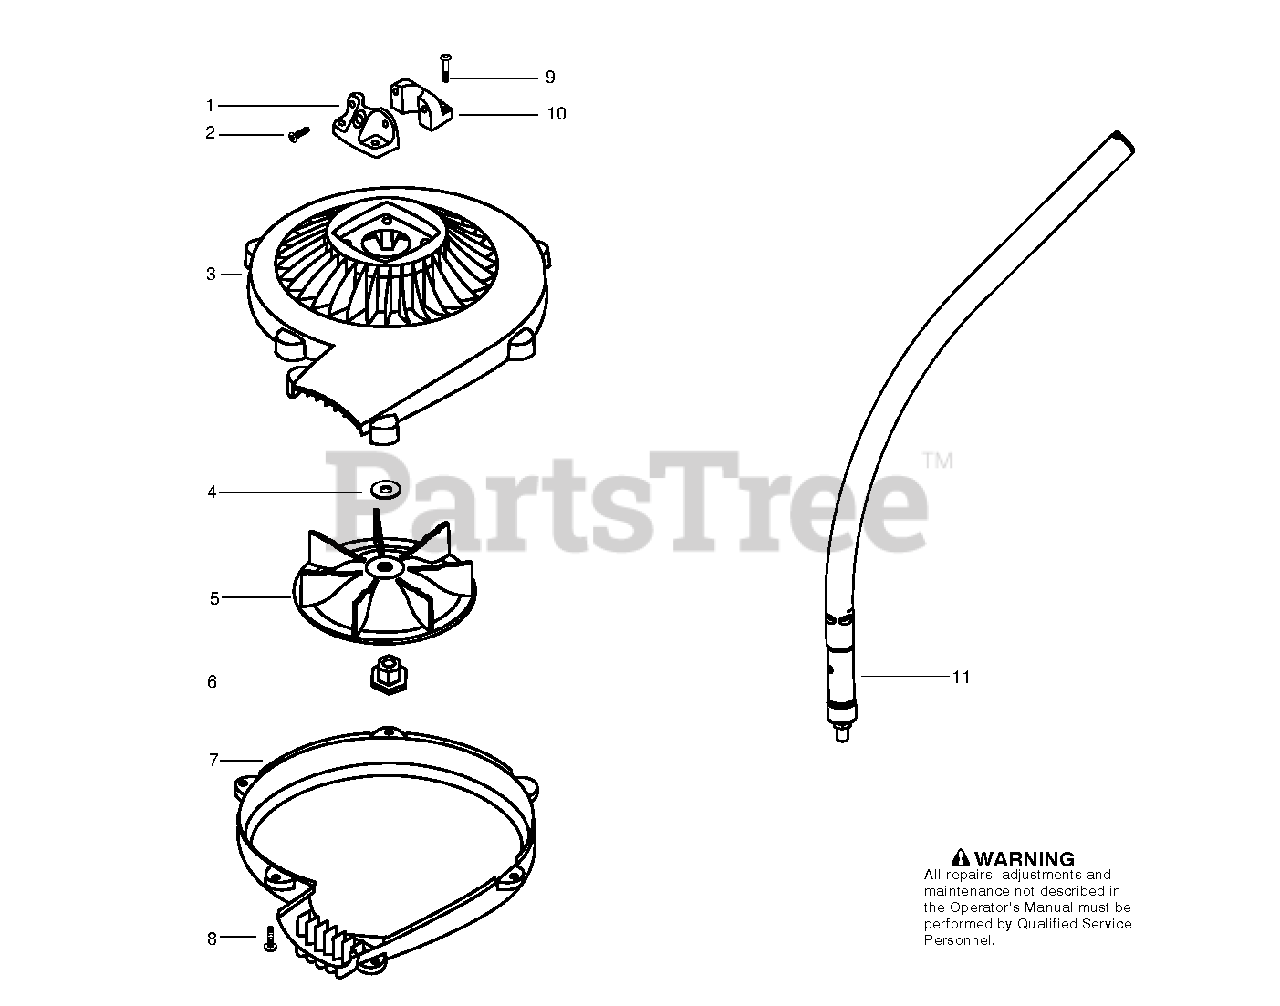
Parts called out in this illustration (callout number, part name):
1	CLAMP,RIGHT
3	HSG,BLOWER (UPPER)
5	IMPELLER
6	ARBOR, IMPELLER
7	HSG, BLOWER (LOWER)
10	CLAMP,LEFT
